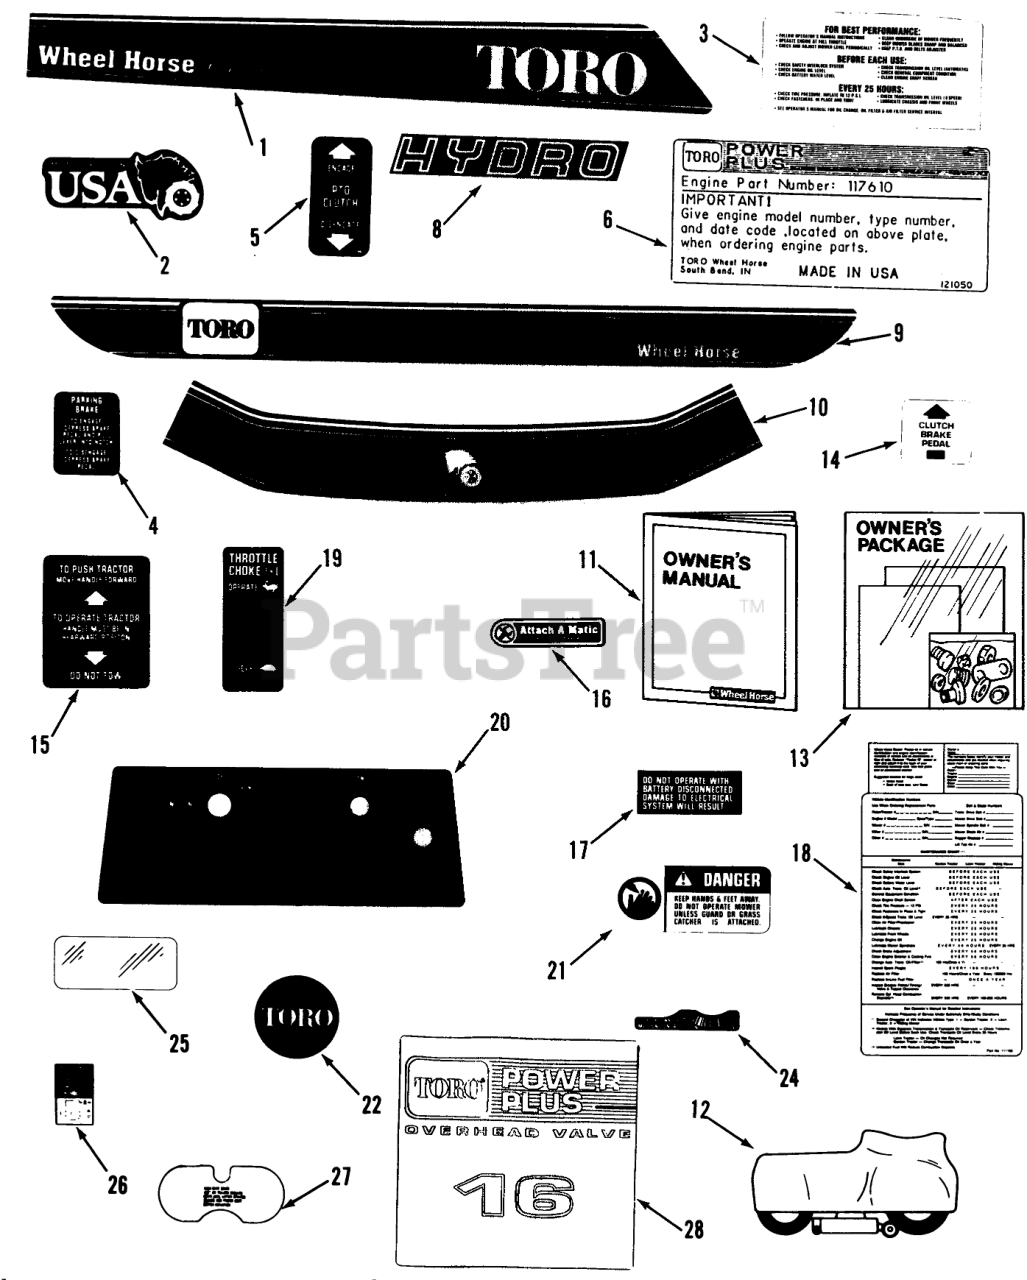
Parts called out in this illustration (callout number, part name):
1	Decal-Hood RH
2	Decal-Made In USA
3	Decal-Hood Rear
4	DECAL PARKING BRAKE
5	DECAL-PTO
6	Decal-Power Plus
8	DECAL-MODEL HYDRO
9	DECAL-FENDER
10	DECAL-FRONT HOOD
11	Operator-s Manual
12	Plastic Cover
13	New Tractor Loose Parts Package
14	DECAL CLUTCH & BRAKE
15	DECAL-PUSH
16	Decal-Attach-A-Matic
17	DECAL ELECT SYSTEM
18	MAINTENANCE-DECAL
19	Decal-Throttle
20	Decal-Back Plate
21	DECAL-DANGER
22	DECAL-TORO ENGINE
24	DECAL-MOTION CONTROL
25	DECAL-OVERLAY
26	DECAL-PTO BELT ADJ
27	DECAL-SEAT LIFTER
28	DECAL-16 OVR HD VAV
